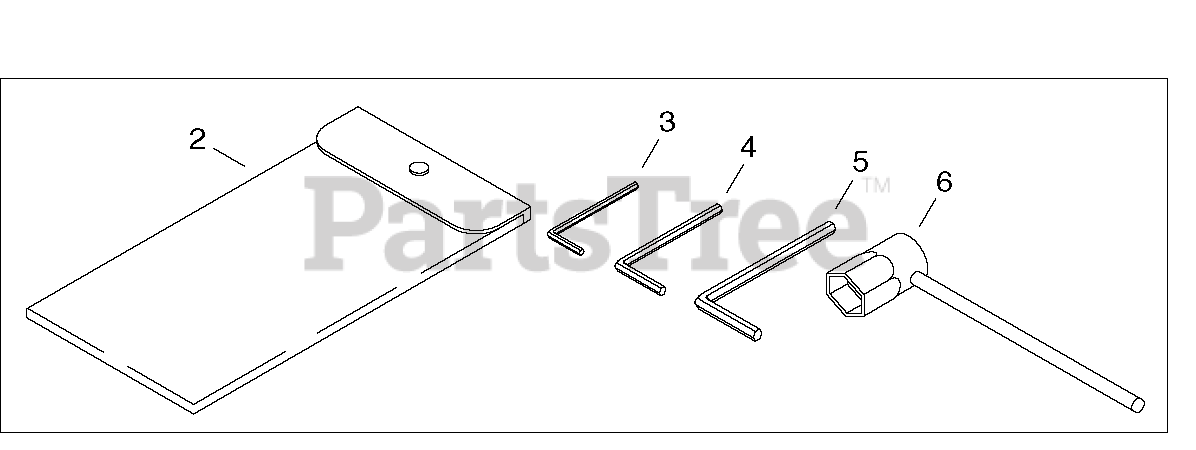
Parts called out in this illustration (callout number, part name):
1	TOOL KIT
2	BAG, TOOL
3	HEX KEY - 3mm
4	HEX KEY - 4mm
5	HEX KEY - 6mm
6	T-WRENCH - 19mm
